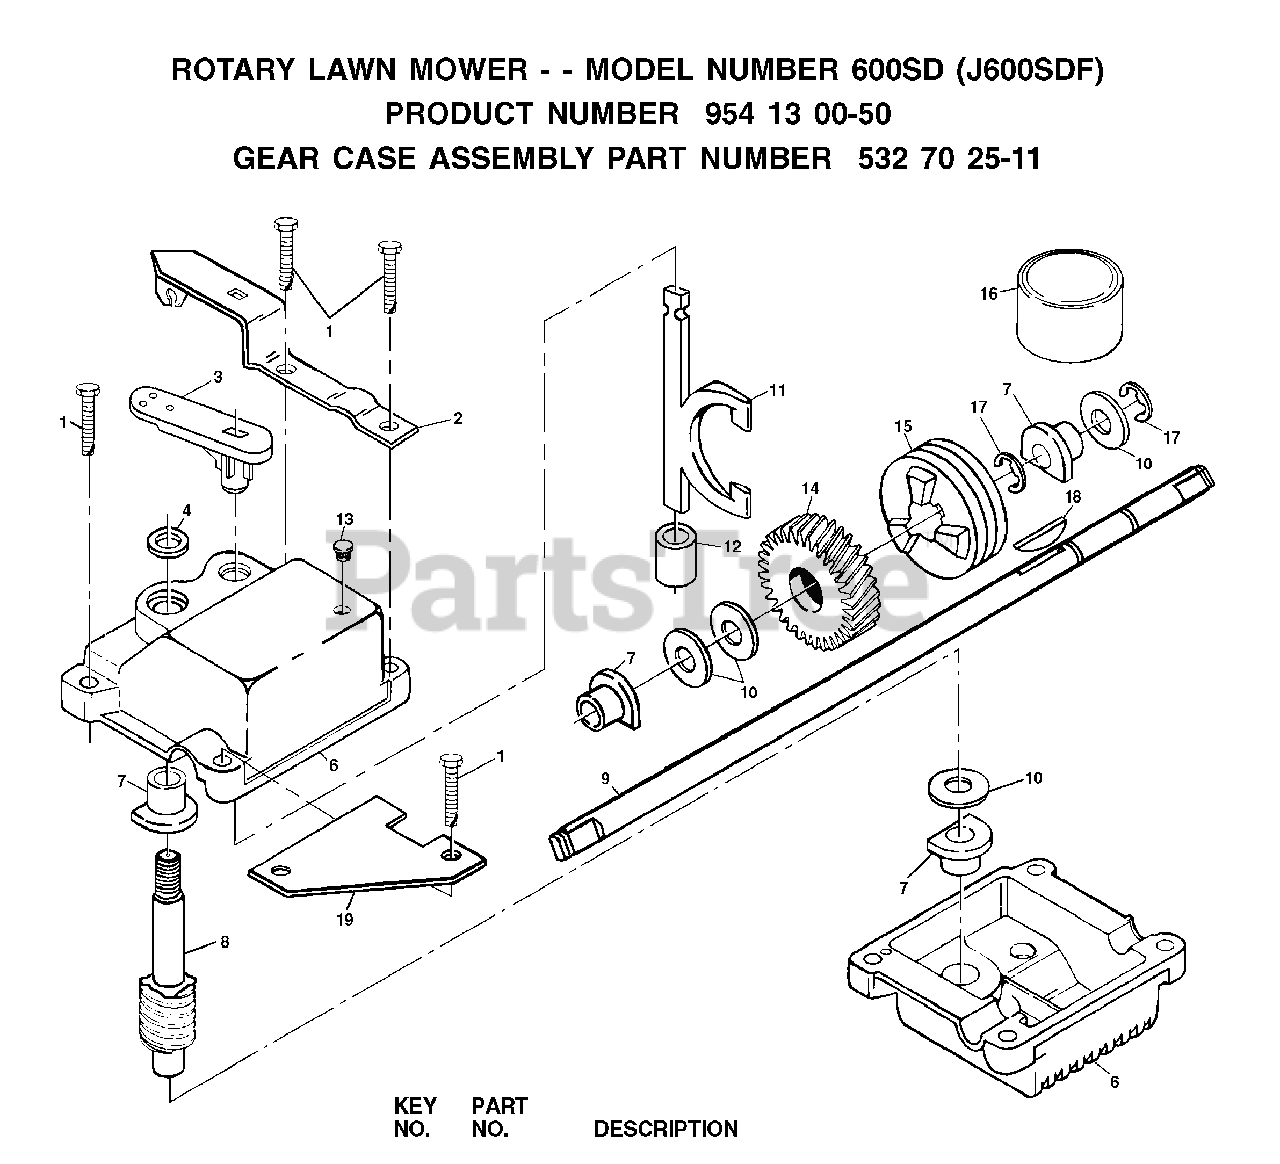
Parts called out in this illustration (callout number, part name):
1	SCREW
2	BRACKET
6	GEAR CASE
8	WORM SHAFT
9	DRIVE SHAFT, 20-5/8"
10	THRUST WASHER
11	YOKE CLUTCH
14	GEAR.HELICAL
15	CLUTCH JAW
16	GREASE
18	HI PRO KEY
19	BRACKET SPRING
